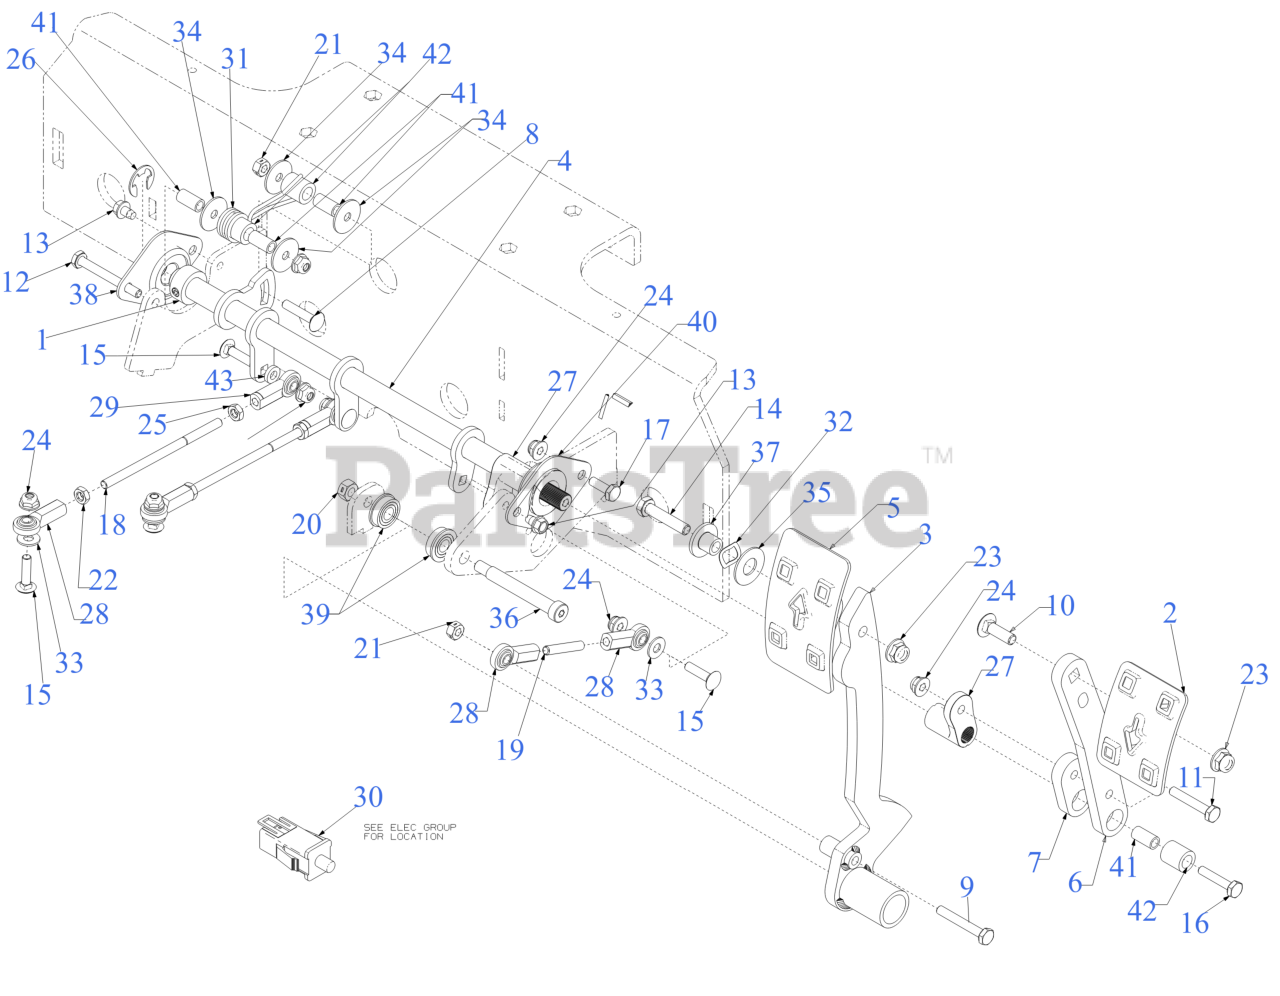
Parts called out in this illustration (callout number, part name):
1	SHAFT COLLAR .625
3	FORWARD PEDAL ARM ASSEMBLY
4	SPEED CONTROL ARM ASSEMBLY
6	REVERSE PEDAL PLATE
7	REVERSE PEDAL SPACER
8	CARRIAGE BOLT 1/4-20 x 1.25 Gr5
9	HEX SCREW 1/4-20 x 1.75
10	CARRIAGE BOLT 5/16-18 x 1.00
11	SCREW 1/4-20 x 1.50 GR8
12	SCREW 1/4-20 x 2.25 GR5
13	SCREW 1/4-20 x .375
14	SCREW 5/16-18 x 1.5 LG
15	SCREW 1/4-20 x 1 GR5
16	SCREW 1/4-20 x 1.25 GR5
17	SCREW 1/4-20X.75 GR5
18	SPEED CONTROL ROD
19	STUD - 1/4-28
20	HEX NUT CENTER
22	HEX JAM NUT 1/4-28
23	FLANGE LOCK NUT 5/16-18
24	FLANGE LOCK NUT
25	JAM NUT 1/4-28 LH
28	END ROD (RH)
30	PLUNGER SWITCH NO/NC
31	TORSION SPRING
32	WAVE WASHER
33	FLAT WASHER
34	FLAT WASHER
35	FLAT WASHER
36	SHOULDER BOLT .375 x 2.50 x 5/16-18
37	DOUBLE SHOULDER SPACER
38	BALL BEARING
39	FLANGE BEARING
40	BALL BEARING
41	SPACER .260 x .375 x .75
42	SPACER-.375X.625X.600
43	SPACER .25 X .50 X .110
